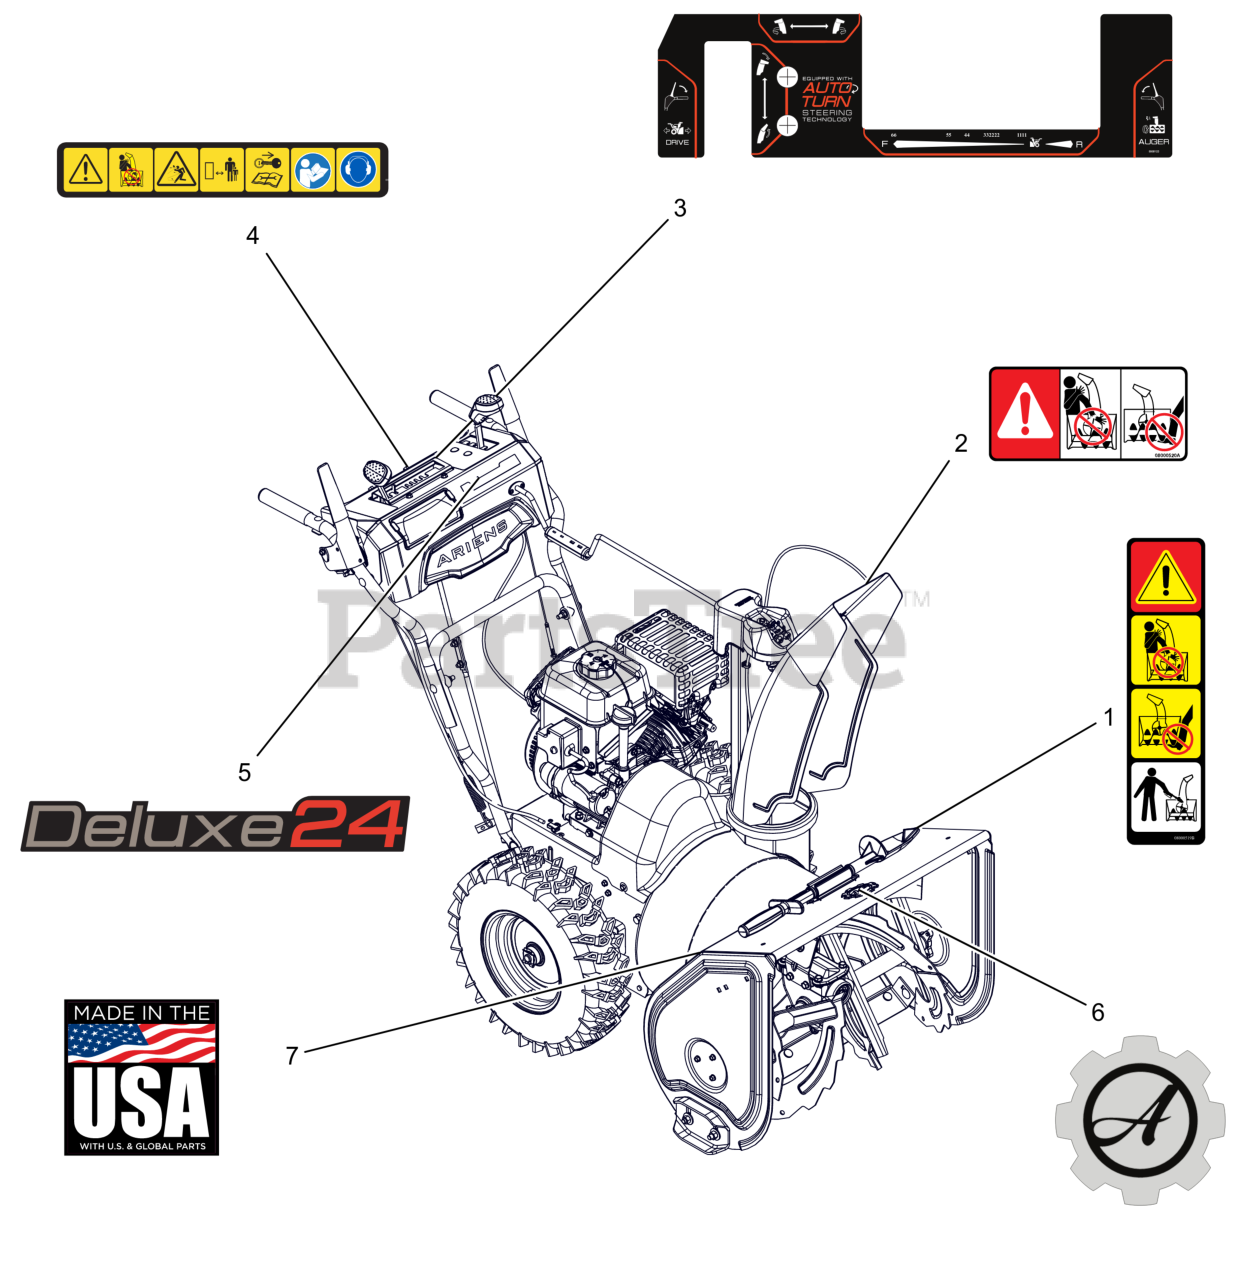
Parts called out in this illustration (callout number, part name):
1	DECAL, DANGER - ROTATING PARTS
2	DECAL, DANGER
3	DECAL,CONTROL-SML,AT,ID
4	DECAL,DASH - SAFETY
5	DECAL, DASH - DELUXE 24
6	DECAL, ARIENS-GEAR BADGE -THK
7	DECAL, MADE IN USA
